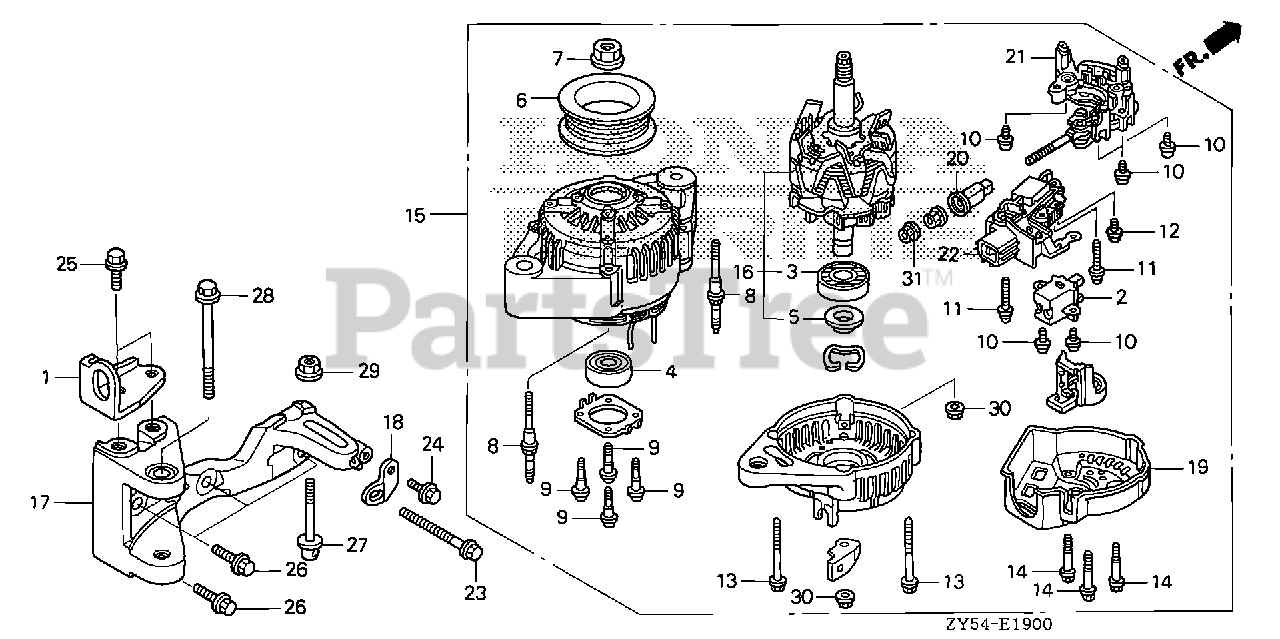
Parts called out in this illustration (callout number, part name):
1	HANGER B, ENGINE
2	HOLDER ASSY., BRUSH
3	BEARING, RR.
4	BEARING, FR.
5	COVER, BEARING
7	NUT, PULLEY LOCK
8	BOLT, STUD
10	SCREW-WASHER
11	SCREW-WASHER (4X25)
13	BOLT-WASHER
15	ALTERNATOR ASSY.
16	ROTOR ASSY.
17	BRACKET, ALTERNATOR
18	STAY, ALTERNATOR
19	END COVER, RR.
20	BUSH, INSULATION
21	RECTIFIER ASSY.
22	REGULATOR ASSY.
23	BOLT, SPECIAL ADJUSTER
24	BOLT, FLANGE (6X16)
25	BOLT, FLANGE (8X20)
26	BOLT, FLANGE (8X28)
27	BOLT, TENSIONER
28	BOLT, FLANGE (10X80)
29	NUT, FLANGE (8MM)
30	NUT-WASHER (5MM)
31	NUT, HEX. (6MM)
